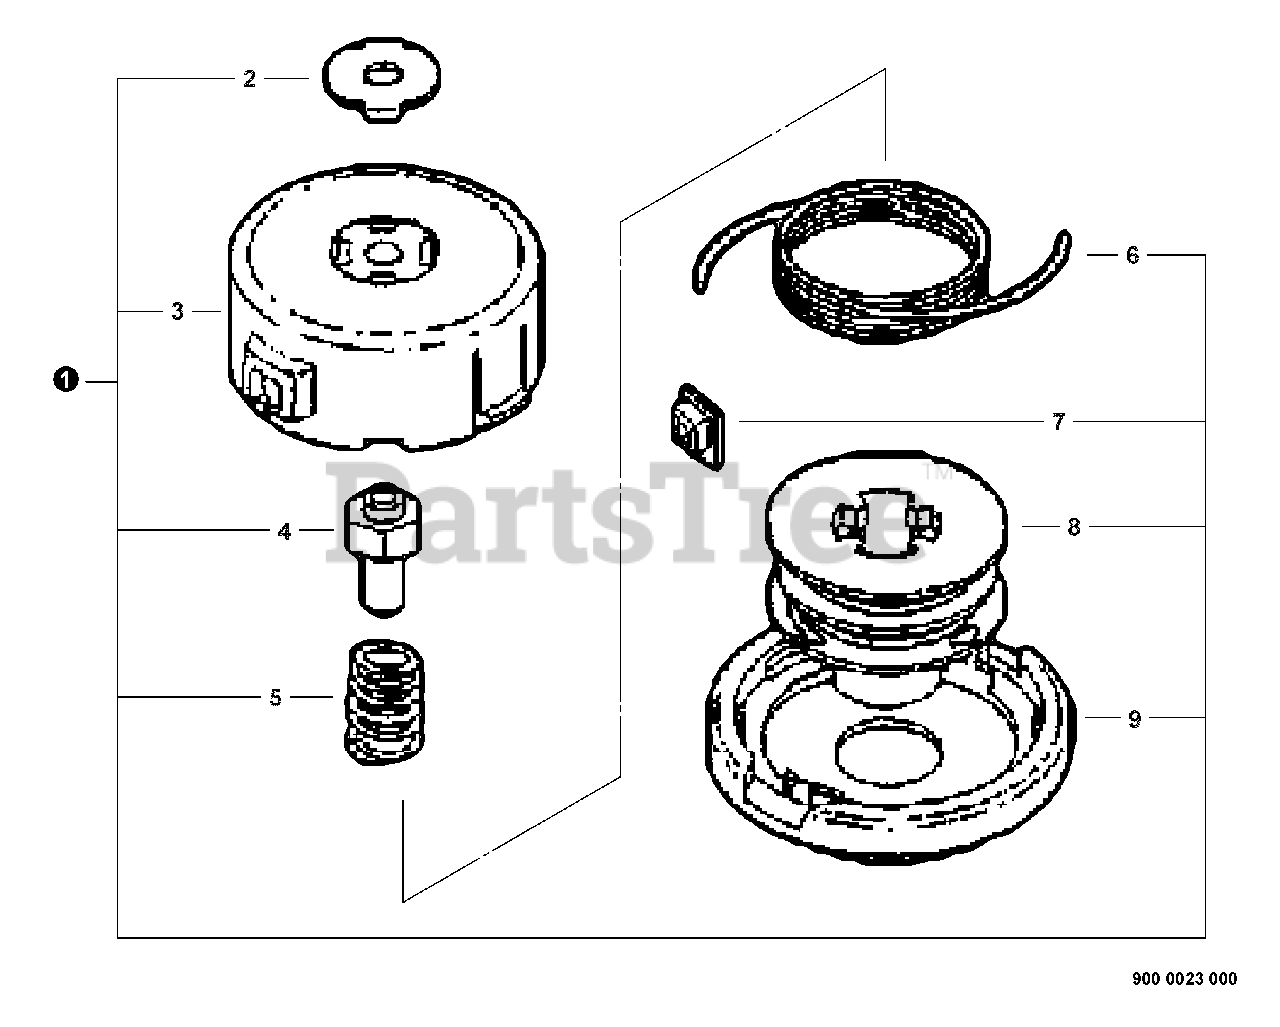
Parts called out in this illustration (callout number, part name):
1	BR-4 TAP &GO TRIMMER HEAD
6	LINE, TRIMMER
9	HOUSING
